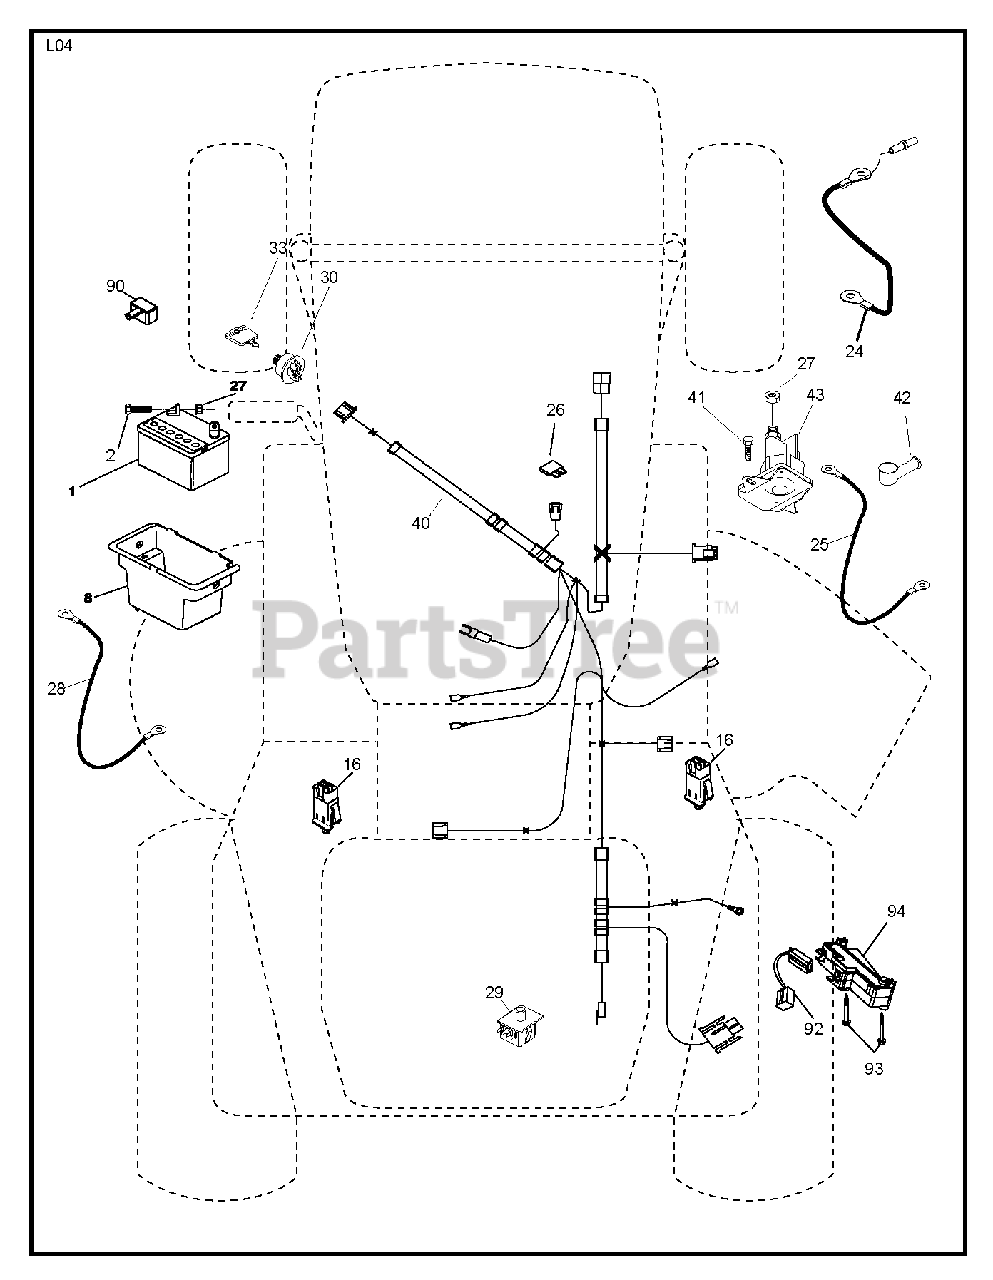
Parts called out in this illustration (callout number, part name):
1	REPL BY 532 12 38-99
2	BOLT.HEX.1/4.X.3/4.DICHROMATE
8	BOX.BATTERY.FENDER
16	SWITCH INTERLOOK PUSH-IN
24	CABLE.STARTER.6GA.11"RED
25	CABLE.GROUND.REAR.BTRY.8GA.44"
26	FUSE 20AMP
27	NUT
28	CABLE GROUND 6 GA. 12" BLACK
29	SWITCH.SEAT.DP W/RAMPS
30	SWITCH.IGN.DELTA.W.LGH.ROS
33	KEY.CHAIN.BLISTER.PACK.GEN.USA
40	HARNESS.IGN.CABLE.REG.
41	BOLT
42	TERMINAL COVER
43	SOLENOID.W/BRASS.PLUNGER
90	COVER.TERMINAL.BATTERY
92	HARNESS.PIGTAIL.CONSLE
93	SCREW.PLASTITE
94	MODULE.REVERSE.ROS
